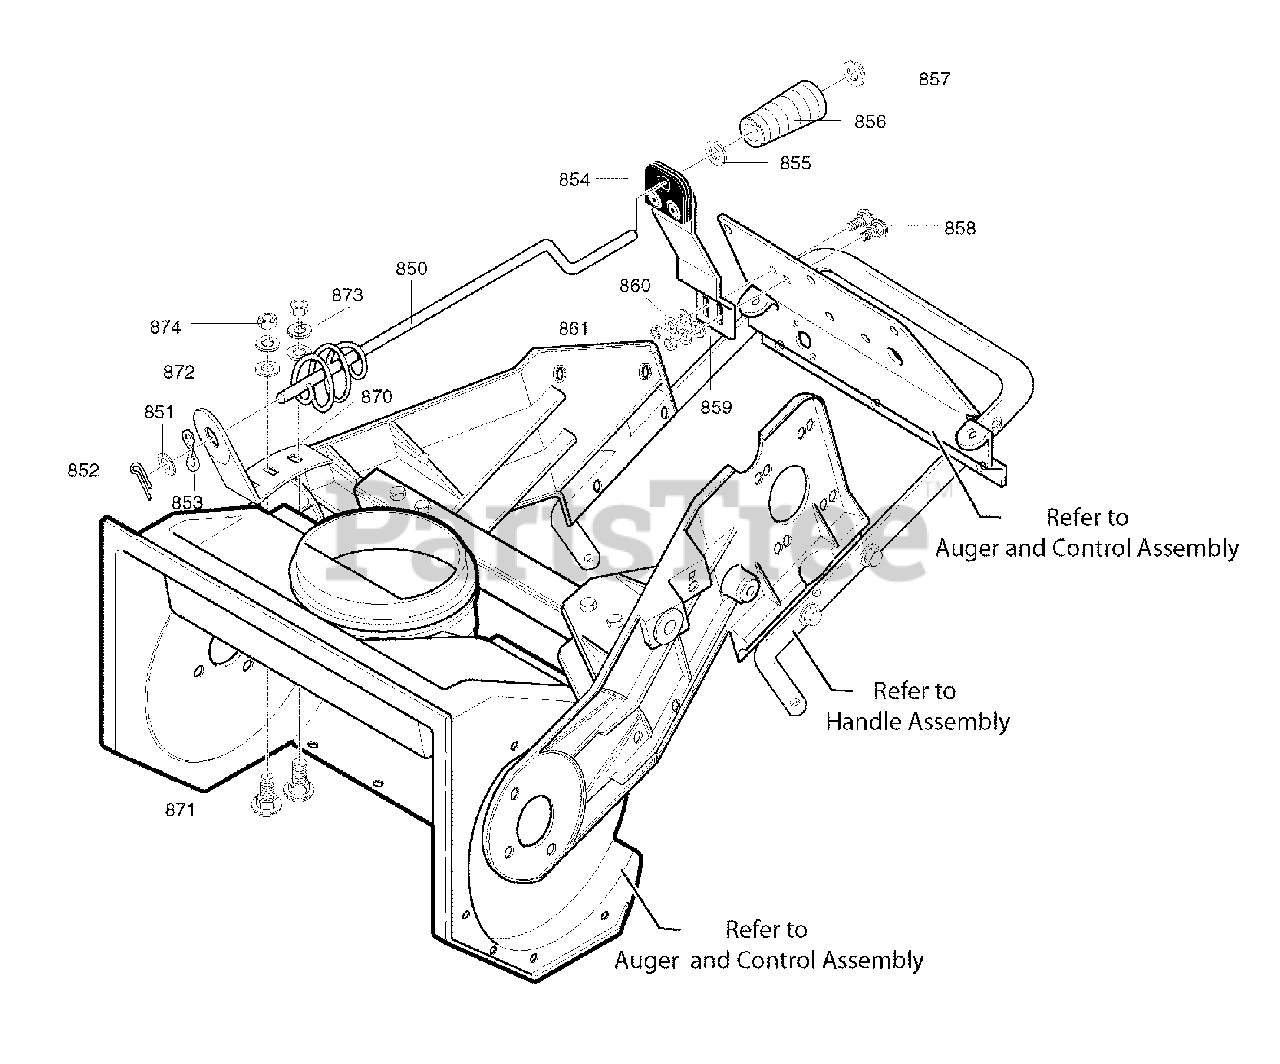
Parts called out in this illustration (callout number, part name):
850	ROD, CHUTE
851	WASHER, FLAT .406 X .81 X .066
852	PIN, COTTER
853	WASHER, CURVED SPRING
854	ASSY, CHUTE CRANK BRACKET
855	WASHER, FLAT .406 X.81 X .066
856	KNOB, SLEEVE
858	BOLT, 1/4-20 X .63 CARRIAGE
859	WASHER, FLAT .349 X .69 X .065
860	WASHER, SPLIT LOCK .31 X .58 X .08
861	NUT, 1/4-20 HEX
870	BRKT, CHUTE ROTATE
871	BOLT, 5/16-18 X .75 CARRIAGE
872	WASHER, FLAT .349 X .69 X .065
873	WASHER, SPLIT LOCK .31 X .58 X .08
874	NUT, 5/16-18 HEX
